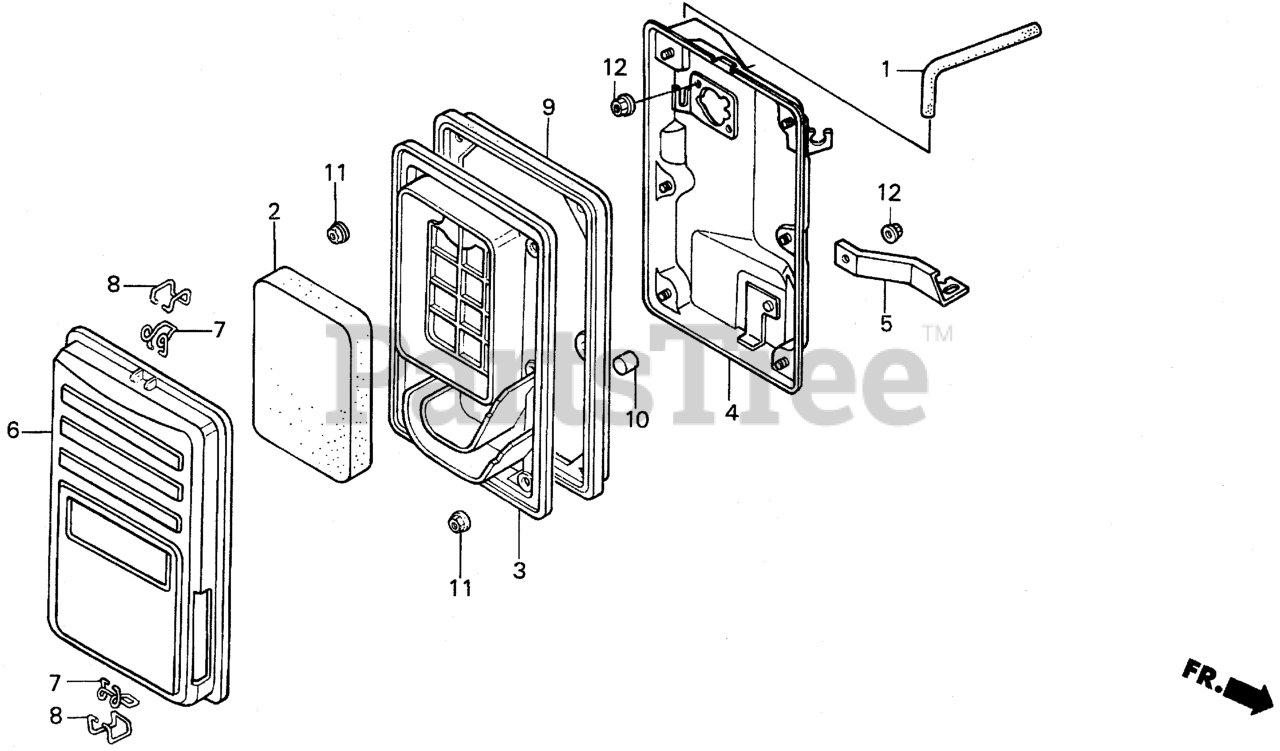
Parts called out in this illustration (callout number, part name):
1	TUBE, BREATHER
2	ELEMENT, AIR CLEANER
3	SEPARATOR, AIR CLEANER
4	HOUSING, AIR CLEANER
5	STAY, AIR CLEANER
6	COVER, AIR CLEANER
7	CLIP A, AIR CLEANER WIRE
8	CLIP B, AIR CLEANER WIRE
9	SEAL, AIR CLEANER
10	FILTER, DRAIN TUBE
11	NUT, FLANGE (5MM)
12	NUT, FLANGE (6MM)
